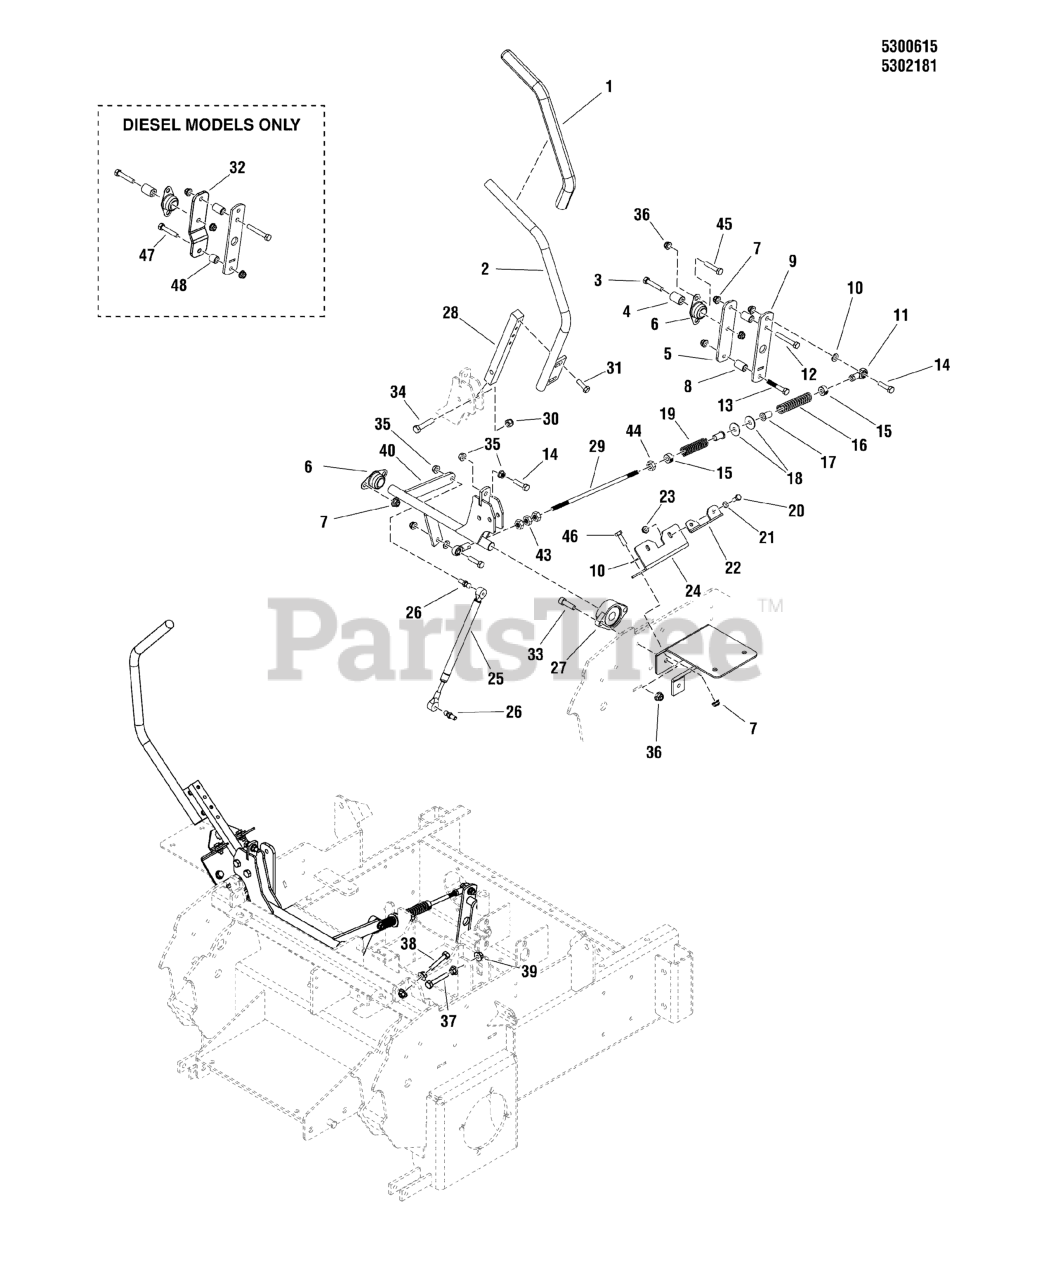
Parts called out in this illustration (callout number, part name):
1	GRIP, FOAM, 3/4" ID, 16"" LONG
1	GRIP, FOAM, 1" ID, 16" LONG
2	WELD, HANDLEBAR - LH - RED
2	WELD HANDLE MOTION CNTRL 13.8 1.0 LH BLK
3	BOLT, 5/16-18 X 1-3/4" GD5 YZ
4	SPACER, .32 X .75 X 1.06, PM
5	BAR, PUMP LINK - INNER - RED
6	BEARING, BRONZE FLANGE, 3/4"
7	NUT, 5/16-18 HEX NYLOCK FLANGE NUT
8	SPACER, .33 X .63 X 1.00, YZ
9	BAR, PUMP LINK - OUTER - RED
10	WASHER, 5/16" SAE
11	BALL JOINT 5/16-24 LH FEMALE STAMPED STL
12	* BOLT, 5/16-18 X 2-1/4 GD5 YZ
13	BOLT, 5/16-18 X 2" GD5 YZ
14	BOLT, 5/16-18 X 1-1/4" GD5 YZ
15	COLLAR, 5/16" Set
16	SPRING, REVERSE RETURN
17	BUSHING, FLANGE 3/8ID X 7/8 LONG
18	WASHER, 5/16" Fender
19	SPRING-COMP, .594ID X 2.68LG X .080WR
20	HHCS, 1/4-20 X 0.625, GR5, ZINC/CLEAR
21	WASHER, 1/4 SAE
22	BRACKET, SWITCH MOUNT - RED
23	NUT, 1/4-20 HEX SERR. FLANGE
24	PLATE, NEUTRAL LOCK - RED
25	DAMPENER, CONTROL,#(P6709/P3610)
26	BALL STUD, 5/16 X .50,# PC-477-2)
27	BEARING, FLANGE
28	MOUNT, CONTROL ARM - BLK
29	ROD, HYDRO CONTROL, OUTFRONT
30	NUT, 3/8-16 HEX NYLON LOCK
31	SCREW-HEX WSHR HD TAPTT5/16-18X0.750BLK
32	BAR, PUMP LINK, OFFSET - RED
33	BOLT, Allen Head, 3/8-16 x 1-1/4
34	BOLT, 3/8-16 X 1-3/4" GD5 CZ
35	NUT, 5/16-18 HEX SERRATED FLANGE (SMALL)
36	NUT, 3/8 - 16 HEX NYLOCK FLANGE
37	BOLT- 5/16-18 X 1-1/2 GD5 TFL
38	BOLT, 5/16-18 X 1-3/4 TFL, GD5 YZ
39	NUT, 5/16-18 HEX SERRATED FLANGE (LARGE)
40	WELD, MOTION CONTROL SHAFT - LH - RED
43	NUT, Hex, 5/16-24
44	NUT, 5/16-24 HEX, LH
45	BOLT, 3/8-16 X 3/4" GD5 CZ
46	BOLT, 5/16-18 X 3/4 GD5
47	BOLT, 5/16-18 X 1-1/2" GD5 YZ
48	SPACER, .33 X .63 X .50, CZ
